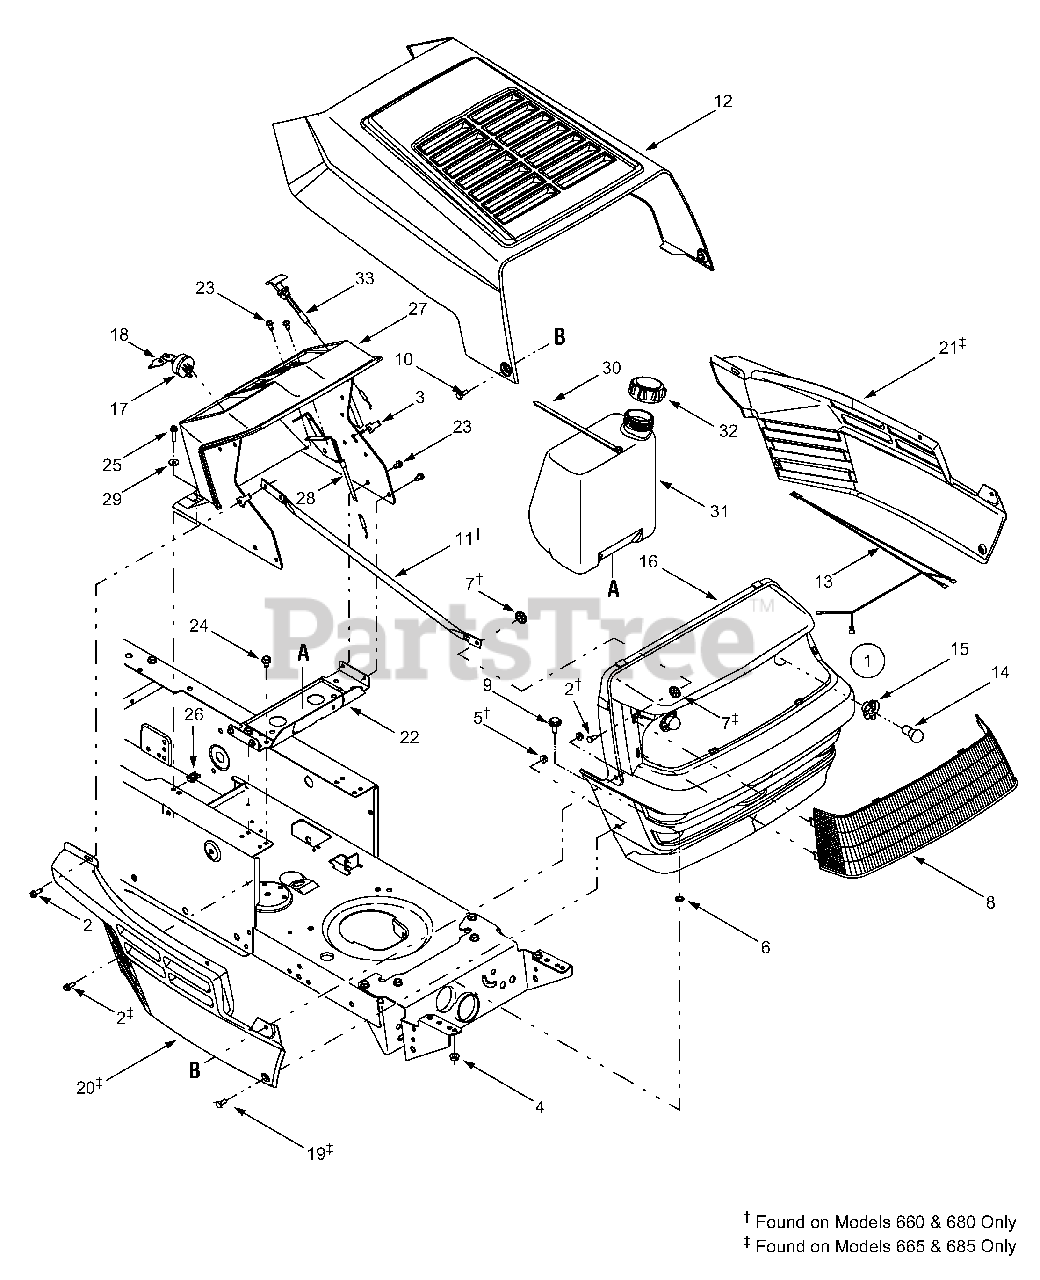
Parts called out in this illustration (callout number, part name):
1	Grille Assembly
2	Self-tapping Screw, 1/4-20 x .75
3	U-type Speed Nut, 1/4-20
4	Flange Lock Nut, 5/16-18
5	Flange Lock Nut, 1/4-20
6	Speed Nut, .3125
7	Push-on Nut, .25
8	Lens
9	Shoulder Screw, 5/16-18 x .625
10	Shoulder Screw, 1/4-20 x .375 /.125
14	Headlamp, 12V
15	Headlamp Socket
16	Grille
17	Ignition Switch, 6-pin
18	Keys (pair)
19	Hex Screw, 1/4-20 x .620
24	Self-tapping Screw, 5/16-18 x .5
25	Self-tapping Screw, 1/4-20 x 1.0
26	U-type Speed Nut, 1/4-20
27	Dash Panel (models w/o choke knob)
28	Throttle / Choke Control, 18.5"
29	Flat Washer, .260 x .720 x .060
30	Cable Tie, 34.75
31	Fuel Tank, 1.5 gal.
32	Fuel Tank Cap
33	Choke Control, 38"
